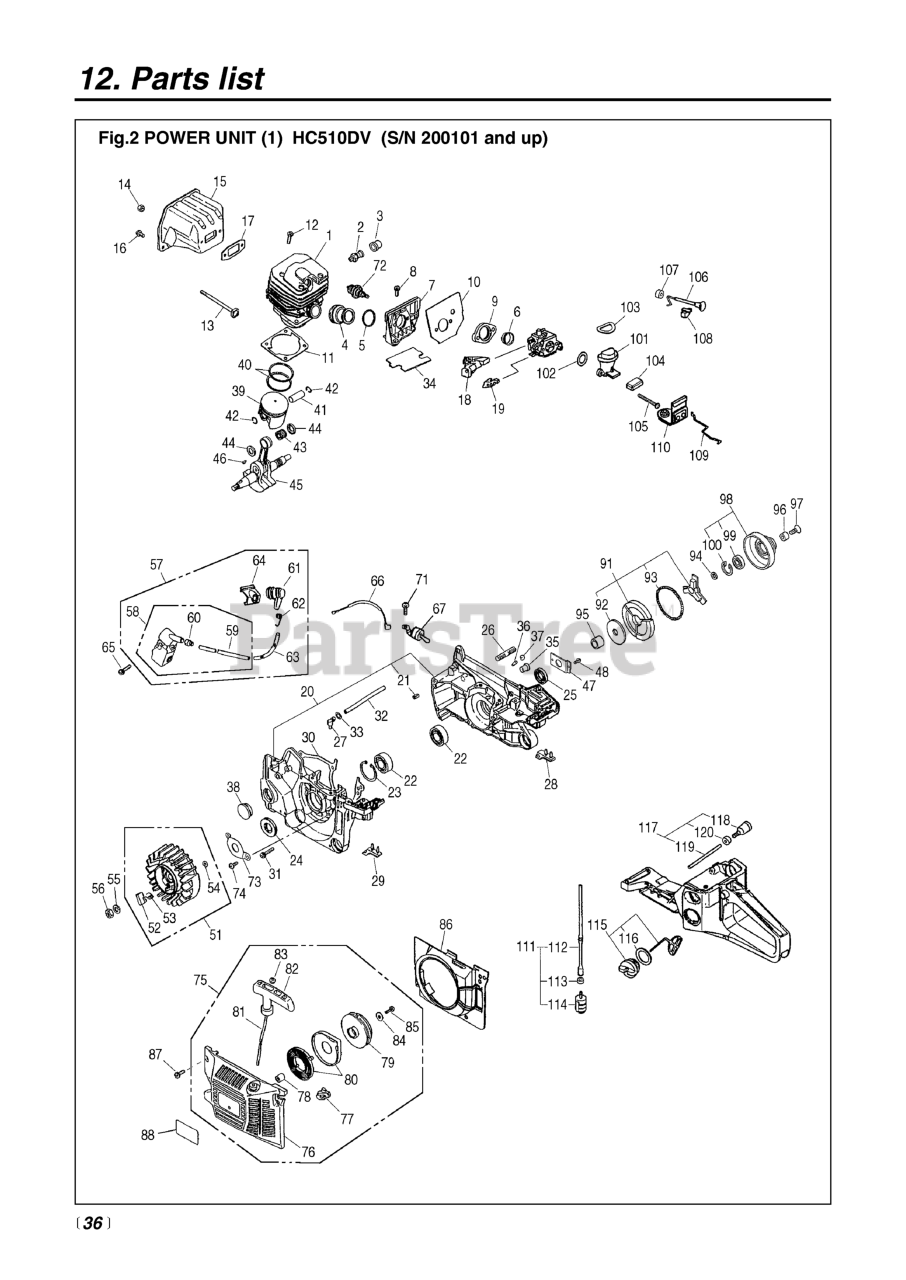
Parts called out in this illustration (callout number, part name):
1	CYLINDER
2	VALVE ASSY.
4	PIPE
5	SPRING
6	GUIDE
8	SCREW (REPLACES 2616-24320)
10	GASKET (RPLS 2880-14360)
11	GASKET, CYLINDER (RPLS -14210)
13	BOLT
14	NUT, MUFFLER (RPLS 3356-15230
16	SCREW
17	GASKET
20	CRANKCASE ASSY.
22	BEARING (REPLACES 2810-21240)
23	RING, SNAP, M35 X 1.5
24	SEAL, OIL
25	SEAL, OIL
28	STOPPER, REAR (RPLS 2670-22510
29	STOPPER, REAR
34	MAT (RPLS 2810-22410)
36	VALVE (RPLS -23120)
37	CLIP
39	PISTON
40	PISTON RING
41	PIN, PISTON
42	RING, SNAP
43	BEARING
44	WASHER, THRUST
45	CRANKSHAFT COMP.
46	KEY
53	SPRING, RETURN
54	RING, SNAP, M4
55	WASHER, M8 x 20
56	NUT (RPLS -43230)
57	COIL ASSEMBLY
58	COIL COMPLETE
59	CORD, HI TENSION
61	CAP, PLUG
62	SPRING PLUG (RPLS 3310-71320)
67	SWITCH ASSY.
71	SCREW
72	PLUG, BPM8Y
74	SCREW, M4 X 10
75	STARTER ASSY.
76	CASE, RECOIL (RPLS 2670-75113)
79	REEL (REPLACES -75211)
80	SPRING COMP
82	KNOB
84	WASHER (USE 181741)
86	COVER COMPLETE
87	SCREW (REPLACES 2616-24320)
91	CLUTCH ASSY (RPLS -51200)
92	PLATE
93	SPRING (RPLS -51230)
98	CLUTCH DRUM ASSY.
100	RING, SNAP, M30 X 1.2
101	MANIFOLD
104	SUPPORTER
106	ROD, CHOKE
107	ROD, CHOKE
108	GUIDE
109	ROD, THROTTLE
114	FILTER ASSY
115	CAP ASSEMBLY
116	GASKET
117	BREATHER ASSY.
118	BREATHER ASSEMBLY
119	PIPE, SUCTION
